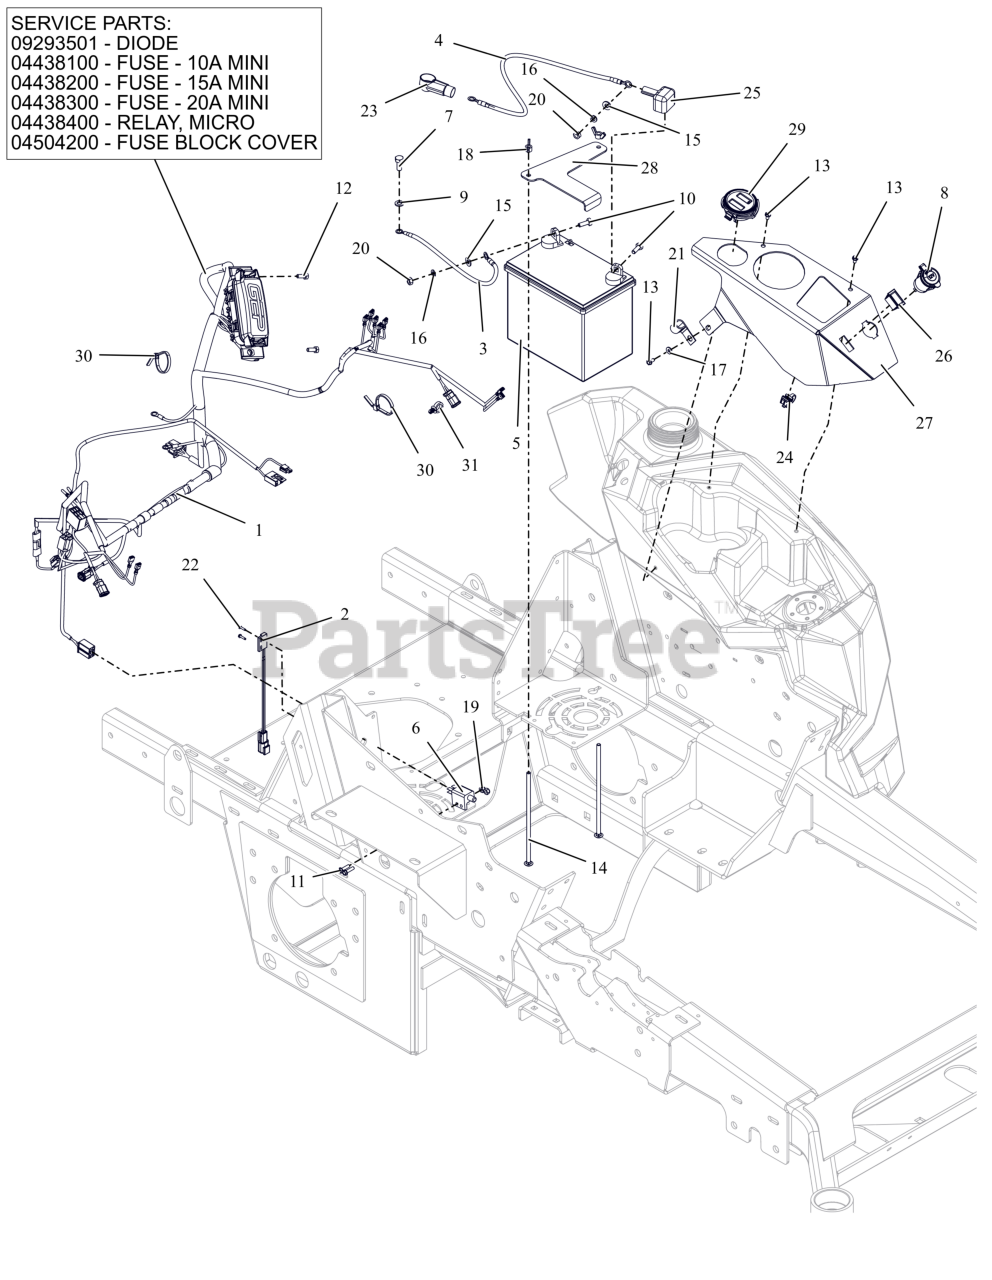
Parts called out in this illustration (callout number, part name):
1	HARNESS, ELECTRICAL 421
1	DIODE, CONNECTOR SHELL
1	FUSE, 7.5 AMP MINI-ATC
1	FUSE,10 AMP MINI-ATC
1	FUSE,15 AMP MINI-ATC
1	FUSE,20 AMP MINI ATC
1	RELAY,MICRO5 TERML W/RESISTOR
1	COVER, HARNESS FUSE/RELAY MOD
1	HARNESS, CLUTCH BREAKAWAY
2	SWITCH, MAGNETIC
3	CABLE, NEGATIVE BATTERY 11.5 LNG
4	CABLE, POS W/(2) .312 RING 16.0 LG
5	BATTERY, 300 CCA 10U1L
6	SWITCH- DOUBLE POLE N.O./N.O.
7	BLT, HEX M8-1.25X20 G8.8 ZCC
8	PORT, 12 VOLT POWER
9	WSHR,LK-REG .312X.078 ZCC
10	BLT, HEX .25-20X.75 G5 ZCC
11	BLT, HWH #10-24X.75 ZCC
12	BLT, HEX M6-1X16 G8.8 ZCC
13	SCR-MCH 10-24X.38 HWHSTAINLESS
14	BTL,RHSN .250-20 X 7.5 G5 ZCC
15	WSHR,FLT .281X.625X.065 ZCC
16	WSHR,LK-REG .250X.062 ZCC
17	WSHR-FL-STL .196X.50X.06 ZC120
18	NUT, LK-WING .25-20 ZCC
19	NUT-LK-NYL #10-24 G2 ZCC
20	NUT-STD .250-20 G2 ZCC
22	SCR-TAP #4-40X.50 HWH ZCC
23	BOOT, .65ID POS
24	TIE, EC23 MOUNT W CABLE
25	INSULATOR
26	SWITCH,BLANK
27	PANEL, LH CONTROL (RED)
28	HOLDDOWN, BATTERY (BLACK)
29	DUAL METER
30	CABLE TIE LG 5-1/2
31	CLIP- PUSH-IN X-MAS TREE CABLE
